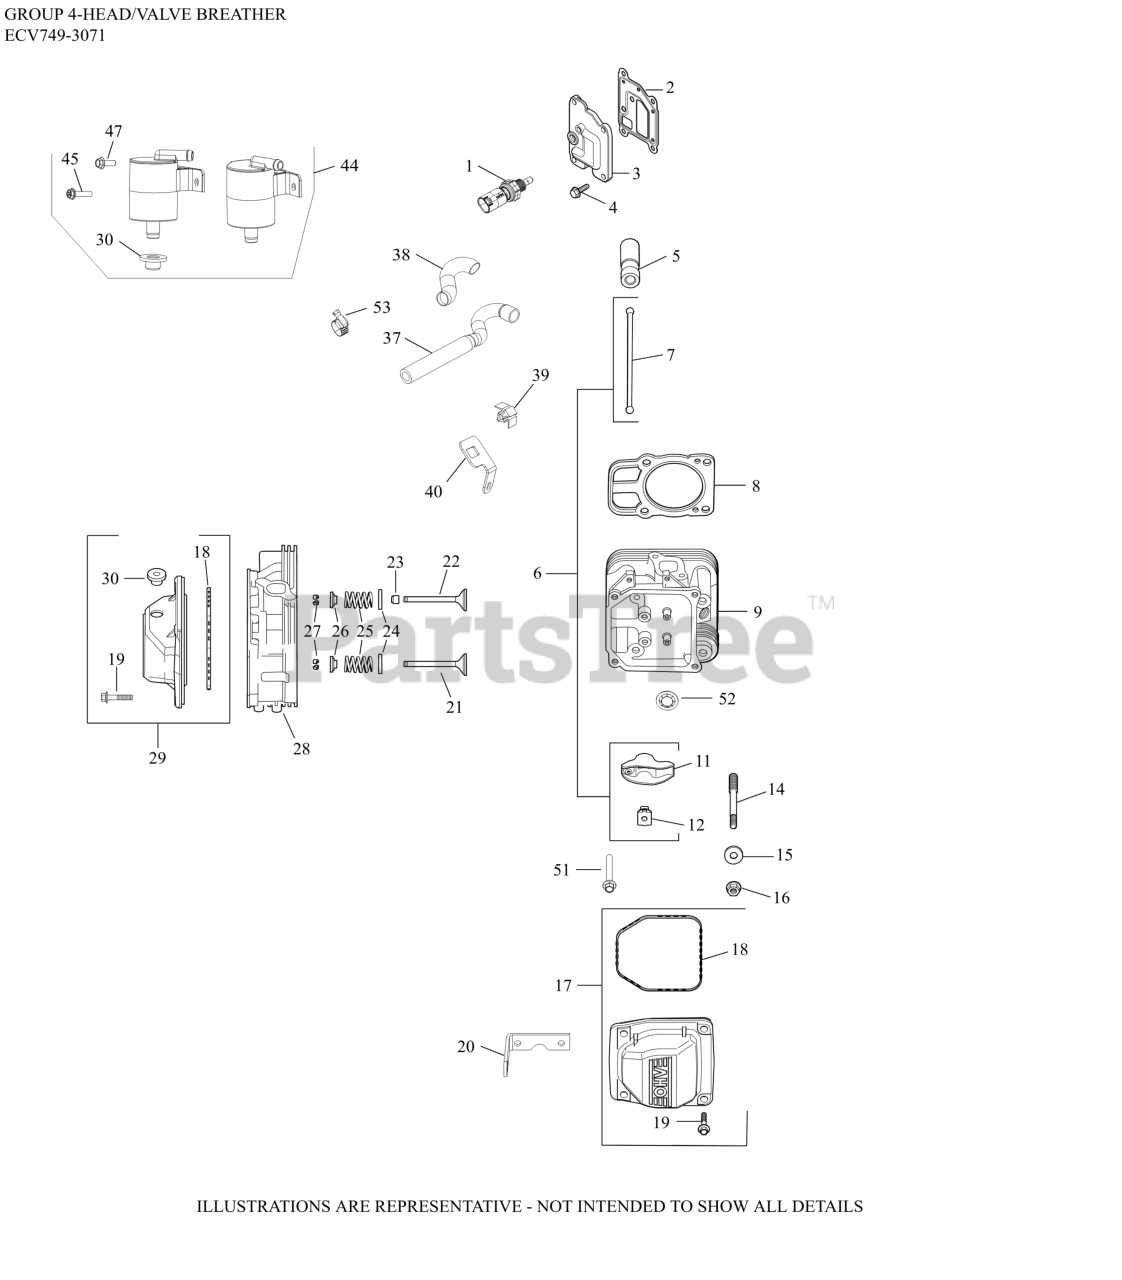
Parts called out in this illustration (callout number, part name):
1	SENSOR, TEMPERATURE
2	GASKET, BREATHER
3	KIT, BREATHER COVER
4	SCREW, THREAD FORMING
5	LIFTER, VALVE HYDRAULIC-USE 25 351 11-S
6	KIT, VALVE TRAIN
7	ROD, PUSH
8	KIT, GASKET CYLINDER HEAD
9	KIT, CYLINDER HEAD (#2)-(#2481804S)
11	ARM, ROCKER
12	PIVOT, ROCKER ARM
14	STUD, M8X1.25
15	WASHER, FLAT 8.6 MM
16	NUT, FLG M8X1.25
17	KIT, VALVE COVER-PLAIN (PLASTIC)
18	O-RING (YELLOW), VALVE CO
19	SCREW, FLG M6X1.0X30
20	STRAP, LIFT
21	VALVE, EXHAUST
21	VALVE, EXHAUST (.25)
22	VALVE, INTAKE (STD)
22	VALVE, INTAKE (.25)
23	SEAL, VALVE BAND
24	RETAINER, SPRING
25	SPRING, VALVE
26	KIT, RETAINER
27	CAP, VALVE SPRING
28	KIT, CYLINDER HEAD (#1)-(#2481803S)
29	KIT, VALVE COVER
30	GROMMET, RUBBER
37	HOSE, BREATHER
38	SLEEVE, ANTI ABRASION-USE 25 431 12-S
39	CLIP, O2 SENSOR
40	BRACKET, OXYGEN SENSOR
44	KIT, BREATHER SEPARATOR
45	SCREW, HEX FLANGE HI-LO
47	SCREW, HI-LOW
51	SCREW, HEX FLANGE (SILVER) M6X1.0X45
52	RETAINER, VALVE GUIDE (KM)
